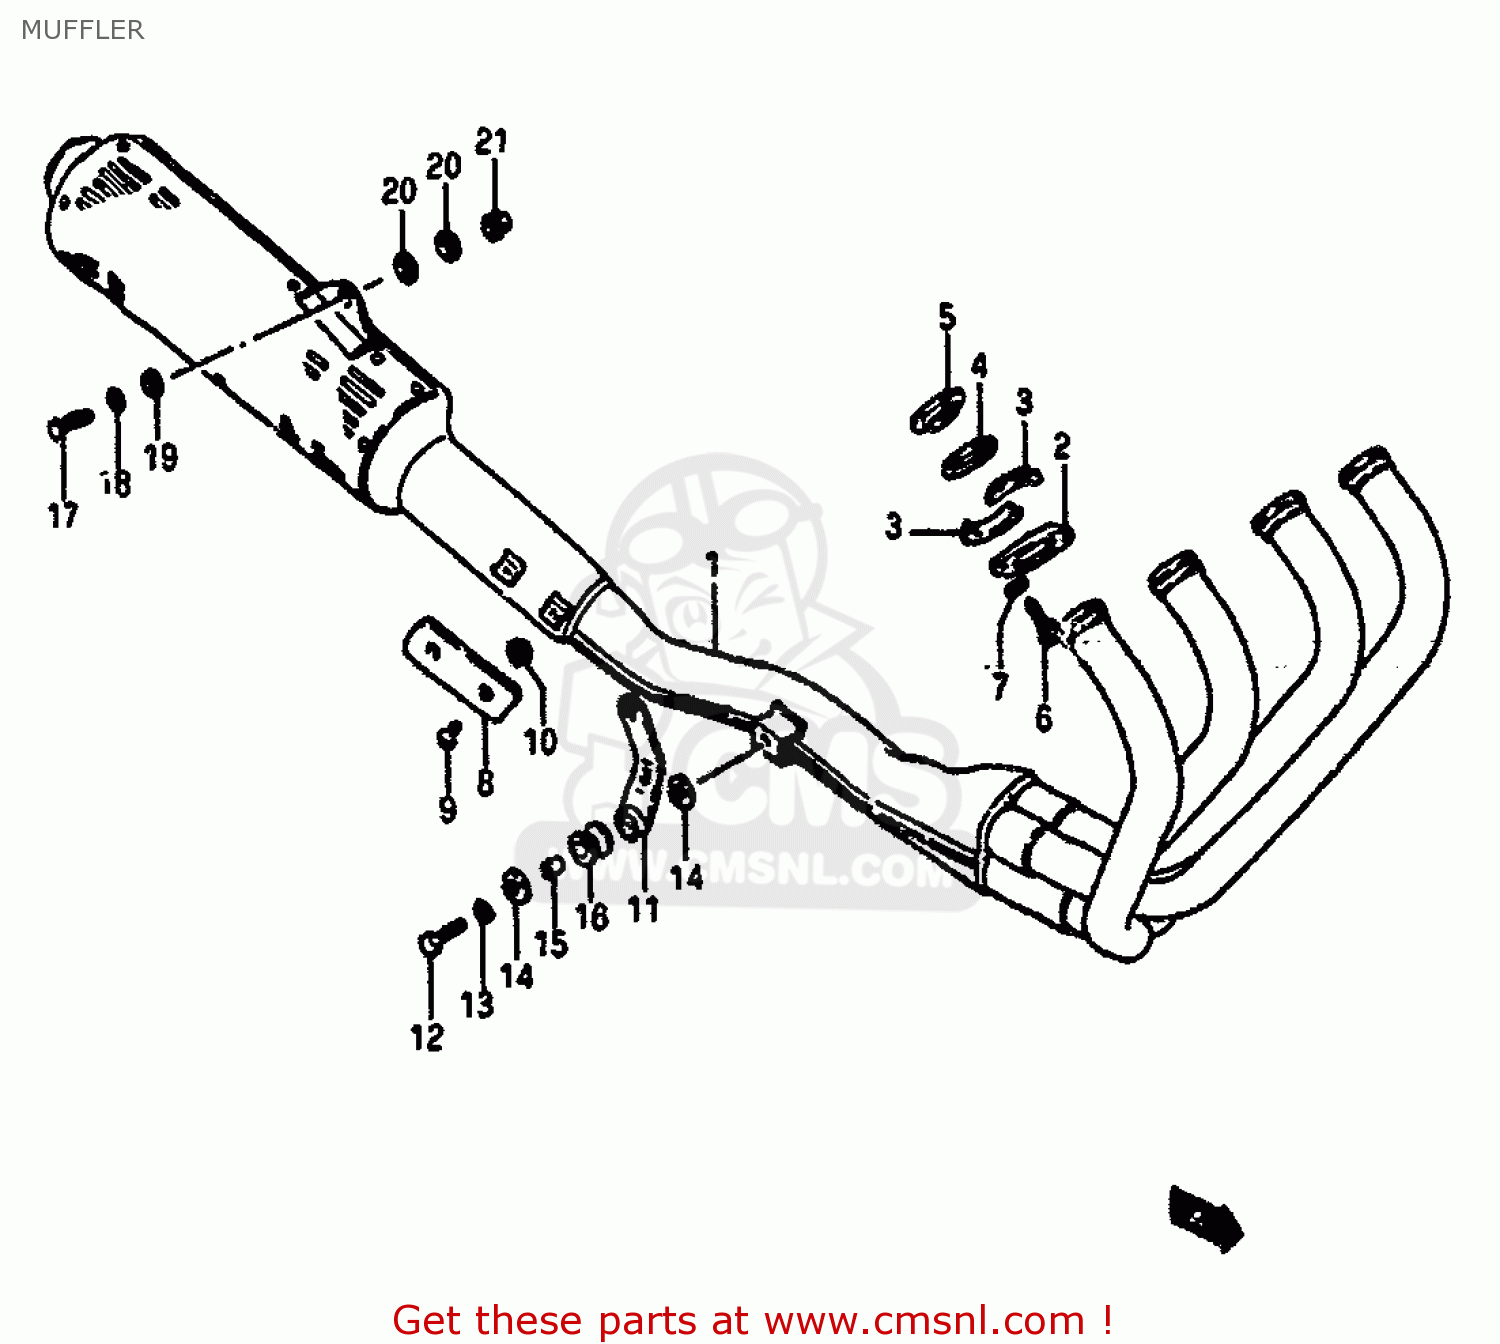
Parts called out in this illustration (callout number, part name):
1	MUFFLER ASSY
2	CLAMP,EXHAUST PIPE
3	PLATE,EXHAUST PIPE
4	GASKET,EXHAUST PIPE (NAS)
5	PLATE,EXHAUST
6	BOLT
7	WASHER
8	COVER,MUFFLER,FRONT
9	SCREW
10	GASKET (NAS)
11	DAMPER,MUFFLER SUPPORT
12	BOLT 8X35
13	WASHER
14	WASHER (8.5X20X1.6)
15	SPACER (8.6X12X17.5)
16	CUSHION
17	BOLT
18	WASHER,LOCK
19	WASHER 10MM
20	WASHER
21	NUT
